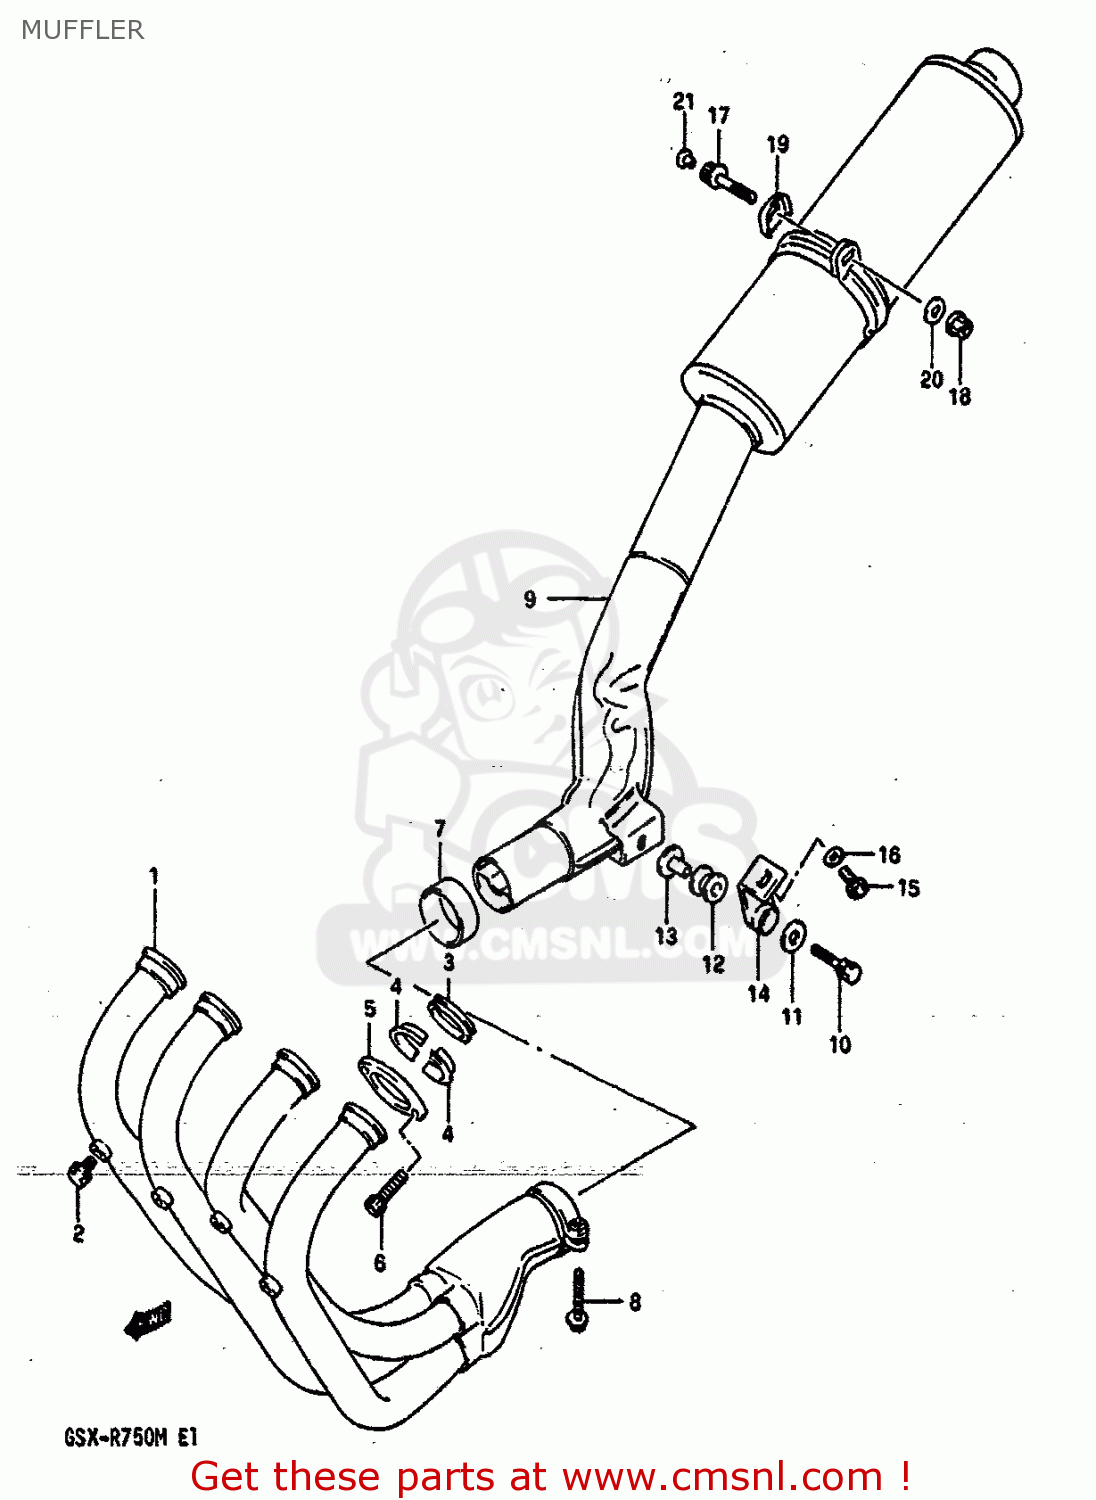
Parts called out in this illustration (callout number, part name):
1	EXHAUST ASSY
2	BOLT, EXHAUST DRAIN
3	GASKET,EXHAUST (NAS)
4	PLATE,EXHAUST PIPE
5	CLAMP,EXHAUST PIPE
6	BOLT
7	CONNECTOR,MUFFLER
8	BOLT 8X45
9	BODY,MUFFLER
10	BOLT 8X35
11	WASHER
12	CUSHION
13	SPACER(8.6X12X18.5)
14	DAMPER COMP,MUFFLER SUPPORT F
15	BOLT(8X20)
16	WASHER
17	BOLT
18	NUT
19	WASHER,MUFFLER SUPPORT
20	WASHER (10.5X24X2.3)
21	CAP(OD:12)
